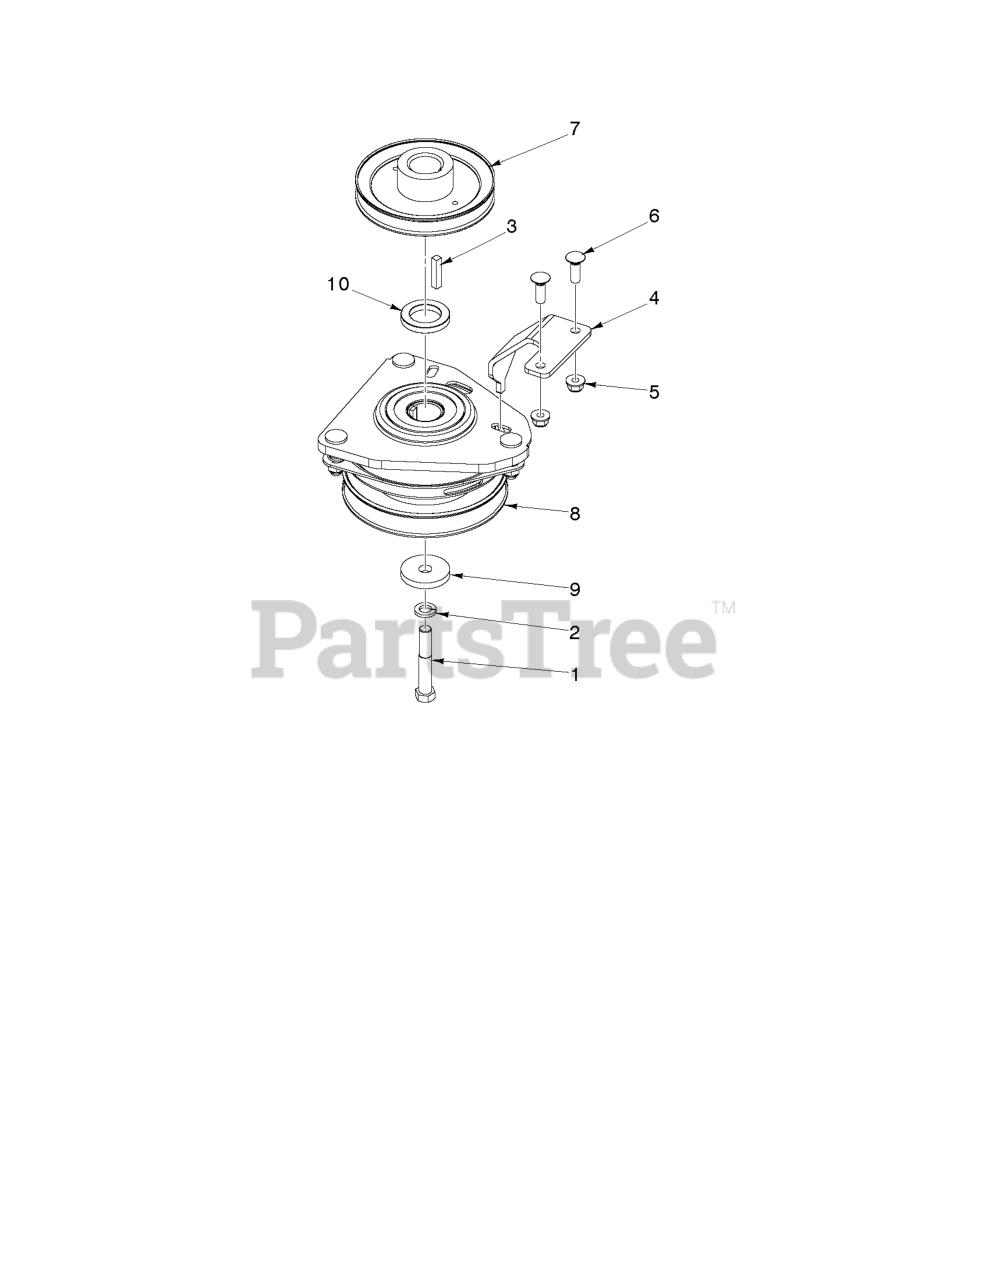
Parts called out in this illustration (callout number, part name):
1	Hardware
2	Washers
3	KEY, 1/4 SQ X 1 1/4
4	Nuts
5	NUT HEXAGON FLANGE 5/16-18 ST
6	Bolts
7	PULLEY.DRIVE.XMSN
8	CLUTCH MZ ZTR GT.48/54"1.125"
9	Washers
10	Spacers
